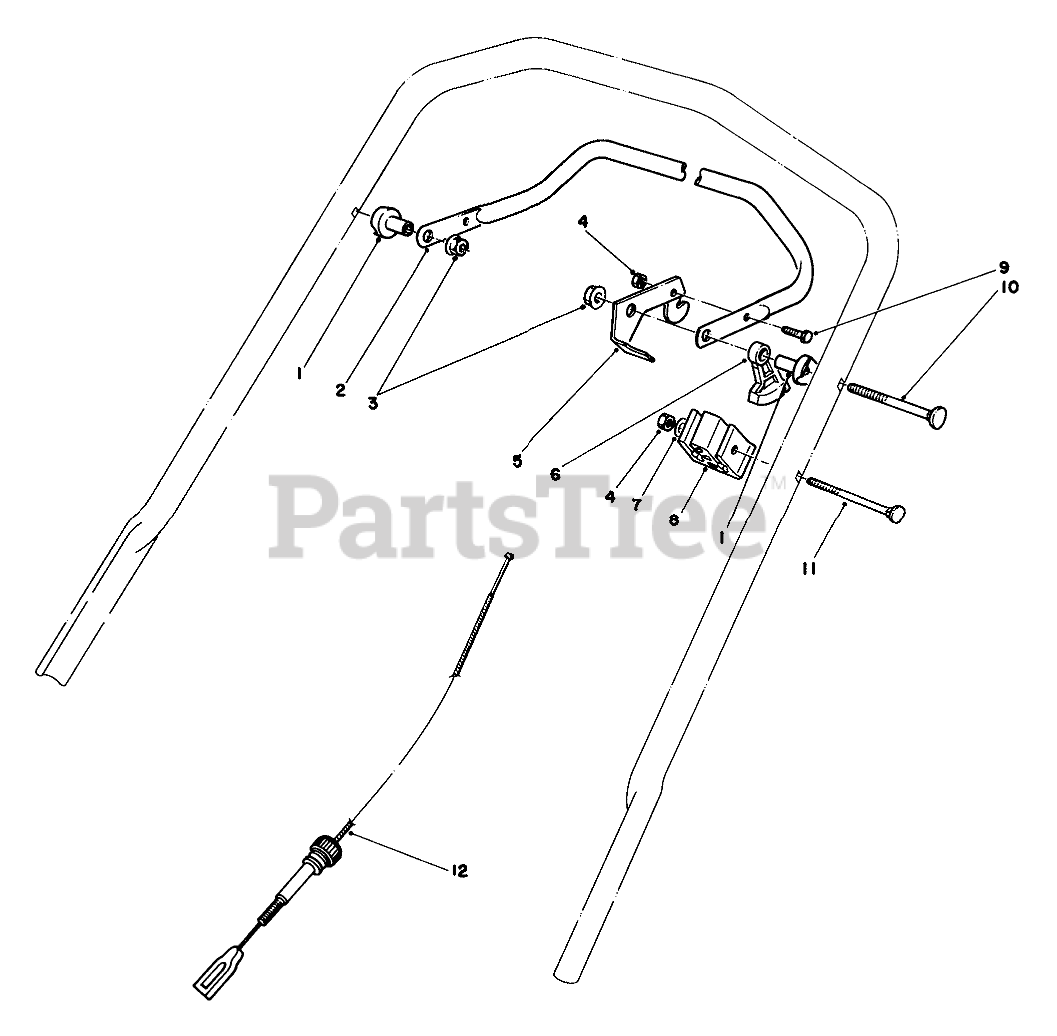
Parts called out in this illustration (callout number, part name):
1	SPACER-SUPPORT
2	Bar-Control
3	NUT-LOCK, NI
4	NUT-LOCK, NI
5	CONTROL LEVER
6	LEVER-TRACTION
7	WASHER-FLAT
8	SUPPORT-CABLE
9	SCREW-HH
10	5/16-18 X 2 HNDLE SCREW
11	HANDLE SCREW
12	CABLE-TRACTION
